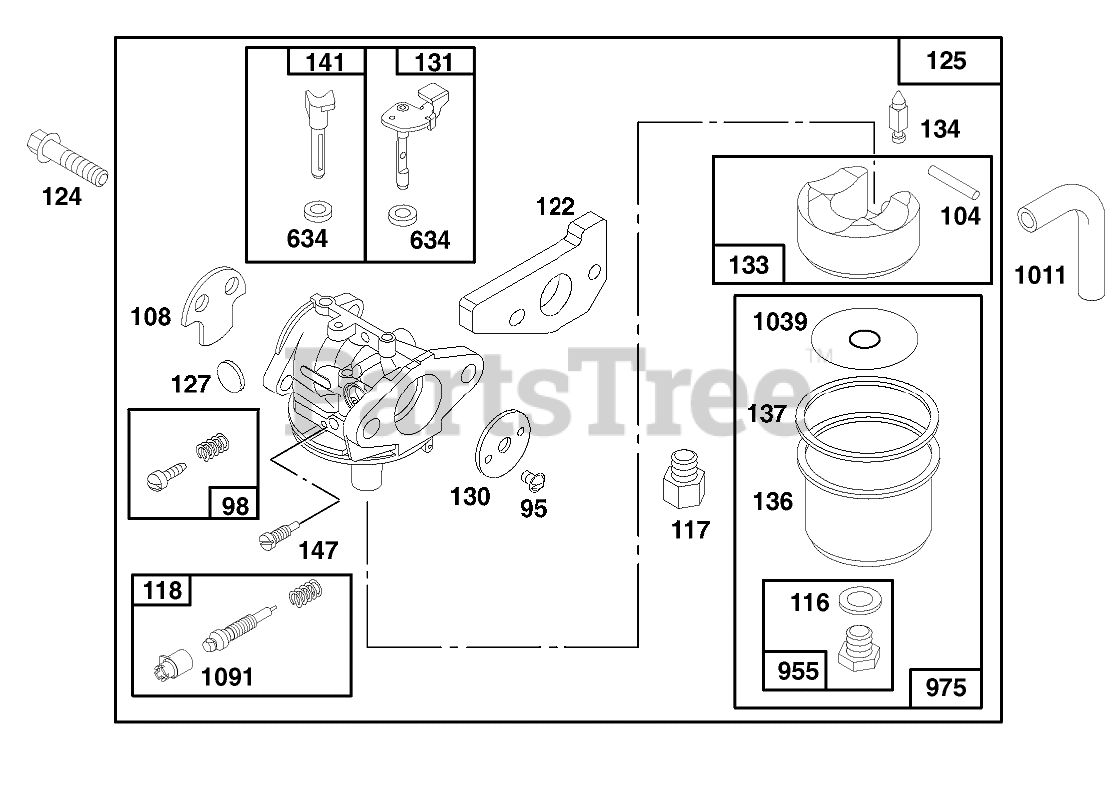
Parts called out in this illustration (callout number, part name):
37	GUARD - FLYWHEEL
95	SCREW - ROUND HEAD
98	IDLE ADJUSTING SCREW
104	FLOAT HINGE PIN
108	VALVE - CHOKE
116	SEALING GASKET
117	Jet-Main
118	VALVE/SPRING - NEEDLE
122	ADAPTER ASSEMBLY
124	HEX HEAD SCREW
125	ASSEMBLY - CARBURETOR
127	PLUG - WELCH
130	THROTTLE VALVE
131	THROTTLE SHAFT
133	FLOAT-CARBURETOR
134	Valve-Inlet (Includes Seat)
136	FLOAT BOWL
137	FLOAT BOWL GASKET
141	CHOKE SHAFT
147	JET - PILOT
634	SEAL WASHER
955	HEX HEAD SCREW
975	CARBURETOR BOWL ASM
1011	VENT TUBE
1039	FLOAT LIMITER
1091	CAP - LIMITER
